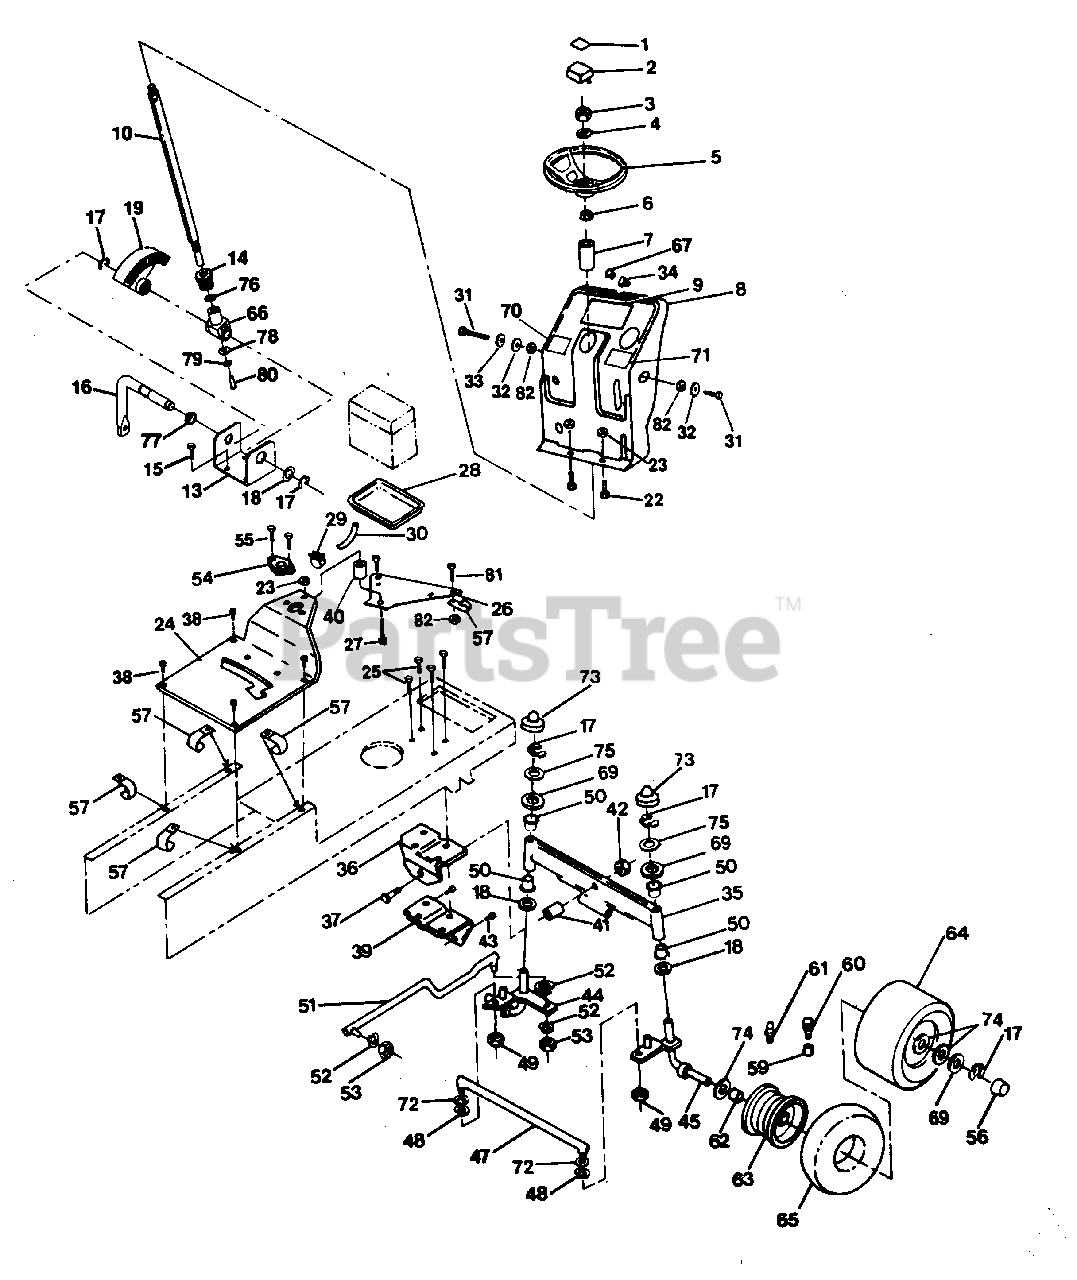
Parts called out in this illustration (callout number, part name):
1	Steering Wheel Cap Decal (AYP part number)
2	Steering Wheel Insert (AYP part number)
3	Hex Nut (AYP part number)
4	Washer (AYP part number)
5	Steering Wheel (AYP part number)
6	Steering Wheel Adaptor (AYP part number)
7	Steering Sleeve (AYP part number)
8	Dash (AYP part number)
9	Dash Decal (AYP part number)
10	Steering Shaft (AYP part number)
13	Steering Bracket (AYP part number)
14	Pinion Gear (AYP part number)
15	Thread Roll Washer Hex Screw (AYP part number)
16	Pitman Shaft (AYP part number)
17	Klip Ring (AYP part number)
18	Thrust Bearing (AYP part number)
19	Sector Gear (AYP part number)
22	Truss Head Crown Screw (AYP part number)
23	Locknut (AYP part number)
24	Saddle (AYP part number)
25	Special Screw (AYP part number)
26	Battery Support Plate (AYP part number)
27	Hex Bolt 5/16-18 x 2 (AYP part number)
28	Battery Tray (AYP part number)
29	Hose Clamp (AYP part number)
30	Tube (AYP part number)
31	Hex Bolt (AYP part number)
32	Washer 13/32 x 13/16 x 16 Ga. (AYP part number)
33	Ext. Tooth Lock Washer (AYP part number)
34	Dash Plug (AYP part number)
35	Front Axle (AYP part number)
36	Rear Saddle Support (AYP part number)
37	Hex Bolt (AYP part number)
38	Thread Roll Washer Hex Screw (AYP part number)
39	Front Saddle Support (AYP part number)
40	Spacer (AYP part number)
41	Front Bearing Axle Spacer (AYP part number)
42	Flange Locknut (AYP part number)
43	Thread Roll Washer Hex Screw (AYP part number)
44	L.H. Spindle (AYP part number)
45	R.H. Spindle (AYP part number)
47	Tie Rod (AYP part number)
48	Lock Washer 5/16 (AYP part number)
49	Hex Nut 5/16-24 (AYP part number)
50	Bearing (AYP part number)
51	Drag Link (AYP part number)
52	Lock Washer 3/8 (AYP part number)
53	Hex Nut 3/8-24 (AYP part number)
54	Steering Bushing (AYP part number)
55	Hex Screw (AYP part number)
56	Front Hub Cap (AYP part number)
57	Fuel Line Clip (AYP part number)
59	Valve Cap (AYP part number)
60	Valve Stem (AYP part number)
61	Grease Fitting (AYP part number)
63	Front Rim (AYP part number)
64	Front Tire (AYP part number)
65	Tube (Not furnished with Tractor)
66	Steering Support (AYP part number)
67	Button Plug (AYP part number)
69	Washer (AYP part number)
70	Clutch Decal (AYP part number)
71	Lift Decal (AYP part number)
72	Washer (AYP part number)
73	Spindle Cap (AYP part number)
74	Washer (AYP part number)
75	Washer (AYP part number)
76	Washer (AYP part number)
77	Snap-in Nyliner (AYP part number)
78	Washer (AYP part number)
79	Lock Washer (AYP part number)
80	Socket Hex Screw (AYP part number)
81	Hex Bolt (AYP part number)
82	Hex Nut (AYP part number)
